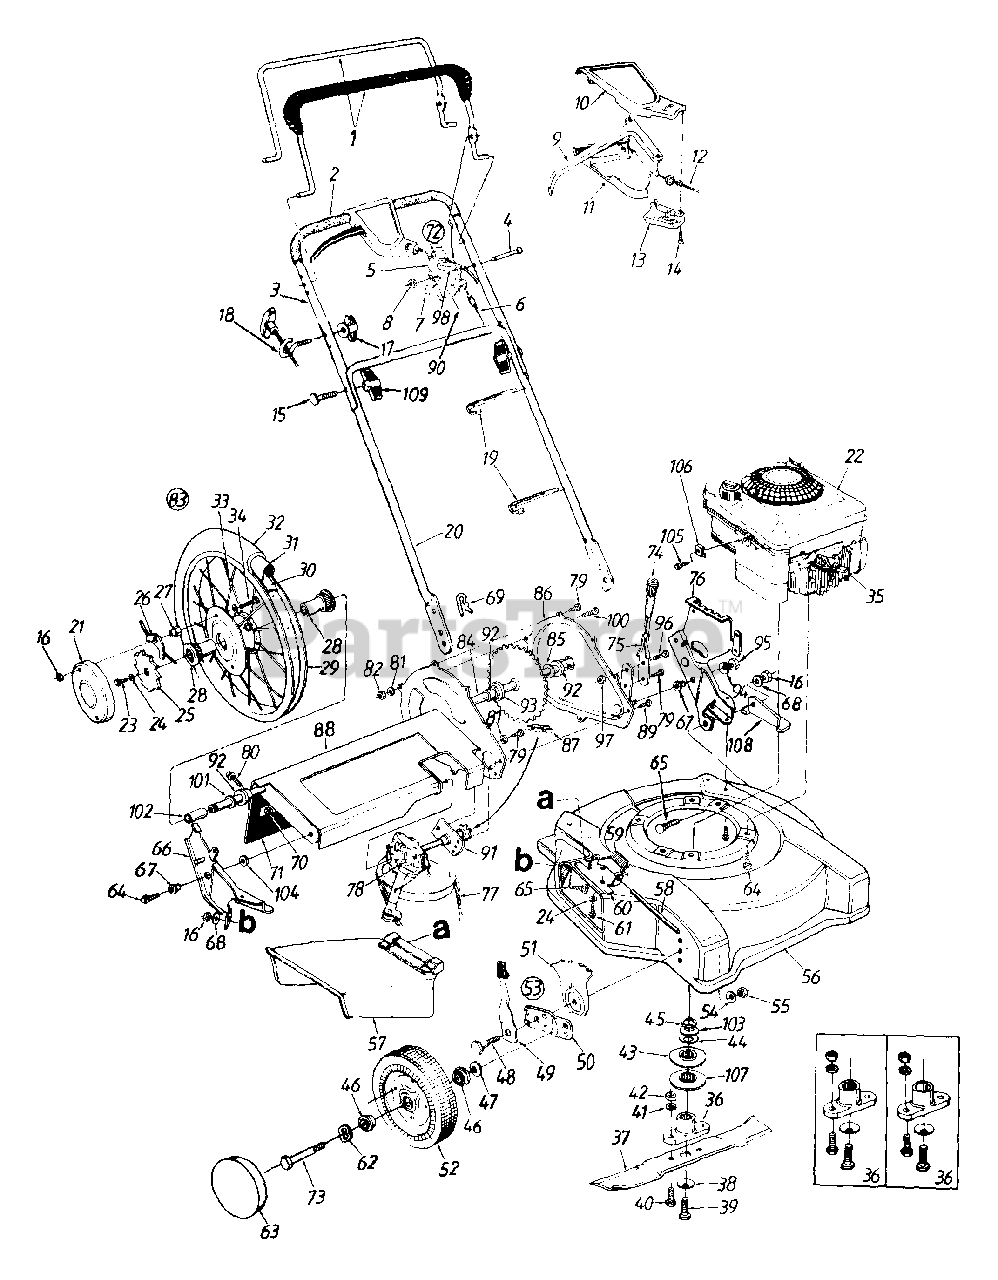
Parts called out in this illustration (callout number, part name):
1	Control Handle Ass'y.
2	Foam Grip
4	Oval C-Sunk Scr.
5	Throttle Body
6	Control Cable - 39" Lg.
7	Spring Wash..66" I.D.
8	Hex L-Nut 1/4-20 Thd.
9	Control Lever
10	Control Cover Half - Upper
11	Control Cover Half - Lower
12	Self-Propelled Cable - 48" Lg.
13	Cable Mounting Cap
14	Fl-"C" Sunk Hd. Tap Scr. #10 x .75" Lg.
15	Curved Hd. Bolt 5/16-18 x 2" Lg.
16	Hex Nut 5/16-18 Thd.
17	Wing Nut 1/4-20 Thd.
18	Rope Guide
19	Cable Tie
21	Wheel Cover
22	Engine
23	Hex Bolt 1/4-20 x .75" Lg. (Gr. 5)
24	Bell-Wash. 1/4" I.D.
25	Wheel Ratchet
26	Pawl and Spring Ass'y.
27	Special Hex Nut 5/16-18 Thd.
28	Flange Bearing .63" I.D.
29	Rim Ass'y. Only 16" x 2.1"
30	Rimstrip 16" x 7/8"
31	Inner Tube 16" x 2.12"
32	Chevron Tire 16" x 2.125"
33	Intern. L-Wash. 5/16" I.D.
34	Hex Bolt 5/16-18 x 1.0" (Gr. 5)
35	Spark Plug Boot
36	Blade Adapter Kit
37	22" Blade
38	Bell-Wash..46" I.D.
39	Hex Bolt 7/16-20 x 1.5" Lg.
40	Hex Bolt 3/8-24 x 1" Lg.
41	L-Wash. 3/8" I.D.
42	Hex Nut 3/8-24 Thd.
43	Pulley Half (2 Rec'd.)
44	Bell-Wash. 1.01" I.D.
45	Crankshaft Spacer
46	Ball Bearing 1/2" I.D.
47	Bell-Wash..38" I.D.
48	Shld. Bolt .5"
49	Spring Lever Ass'y. w/Knob
51	Height Adj. Plate
52	Wheel Ass'y. Comp.
53	Height Adj. Ass'y. Comp.- R.H.
54	Bell-Wash..39" I.D. x 1.38"
55	Hex Nut 3/8-16 Thd.
58	Hinge Pin
59	Torsion Spring
60	Adapter Plate
61	Hex TT-Tap Scr. 1/4-20 x .5"
62	Wave Wash..51" I.D. x .78"
63	Hub Cap
64	Hex TT-Tap Scr. 3/8-16 x 1"
65	Carriage Bolt 5/16-18 x .62" Lg.
66	Handle Brkt. Ass'y.- R.H.
67	Shld. Spacer .5" x .10"
68	Bell-Wash. 5/16" I.D.
69	Intern. Cotter Pin 5/16" Dia.
70	Retaining Strip
71	Rear Flap
72	Throttle Box Comp.
73	Front Axle Bolt
75	Height Adjustment Lever
78	Transmission Comp. (See Breakdown)
79	Hex B-Tap Scr. 1/4 x .38" Lg.
80	Hex AB-Tap Scr. 1/4 x .62" Lg.
81	L-Wash. 1/4" I.D.
82	Hex Nut 1 4-20 Thd.
83	Wheel Ass'y. Comp.
84	Sprocket and Axle Ass'y.
85	Fl-Wash..635" I.D. x 1.0" O.D.
90	Throttle Cable
92	Hex Flange Brg..631" I.D.
93	Spacer .63" I.D. x 1.25"
94	Fl-Wash..385" I.D. x.87" O.D.
95	Hex L-Nut 3/8-24 Thd.
96	Hex Bolt 3/8-16 x .62" Lg.
97	Flanged L-Nut 3/8-16 Thd.
98	Throttle Lever
100	Hex Bolt 1/4-20 x .5" Lg.
101	Fl-Wash..632" I.D. x.943"
102	Spacer .628" I.D. x .875"
103	Bell-Wash. 1.01" I.D.
104	Fl-Wash..38" l.D. x 1" O.D.
105	Wash. Hd. Scr. #10-32 x .62" Lg.
106	Casing Clamp
107	Lower Pulley Half
108	Deck Bracket
109	Hand Knob
